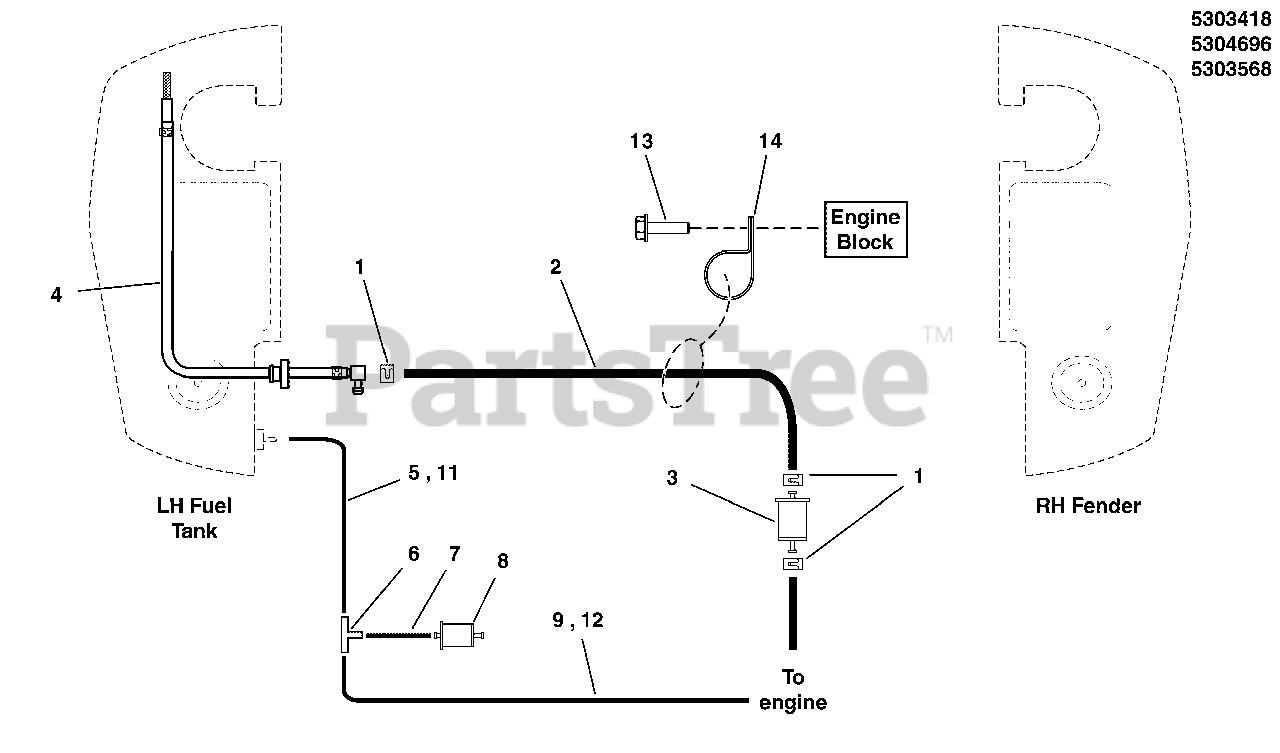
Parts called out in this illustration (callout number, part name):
1	CLAMP, HOSE, EXTERNAL, 1/2 - RED
2	HOSE, 1/4" FUEL, 23.00"
2	HOSE, 1/4" FUEL, 4.00"
3	FUEL FILTER (SV)
4	ASSM, FUEL HOSE, 26
5	HOSE, VAPOR, 5MM ID, 36.00 LG
6	FITTING, 3/16" TEE, BARB TYPE, HDPE
7	HOSE, VAPOR, 5MM ID, 2.00 LG
8	FILTER, Fuel
9	HOSE, VAPOR, 5MM ID, 9.00 LG
11	HOSE, VAPOR, 5MM ID, 17.50 LG
12	HOSE, VAPOR, 5MM ID, 26.00 LG
13	SCREW, Hex Washer Head, 1/4-20 x 5/8
14	CLAMP, VINYL INSULATED, 1.00
